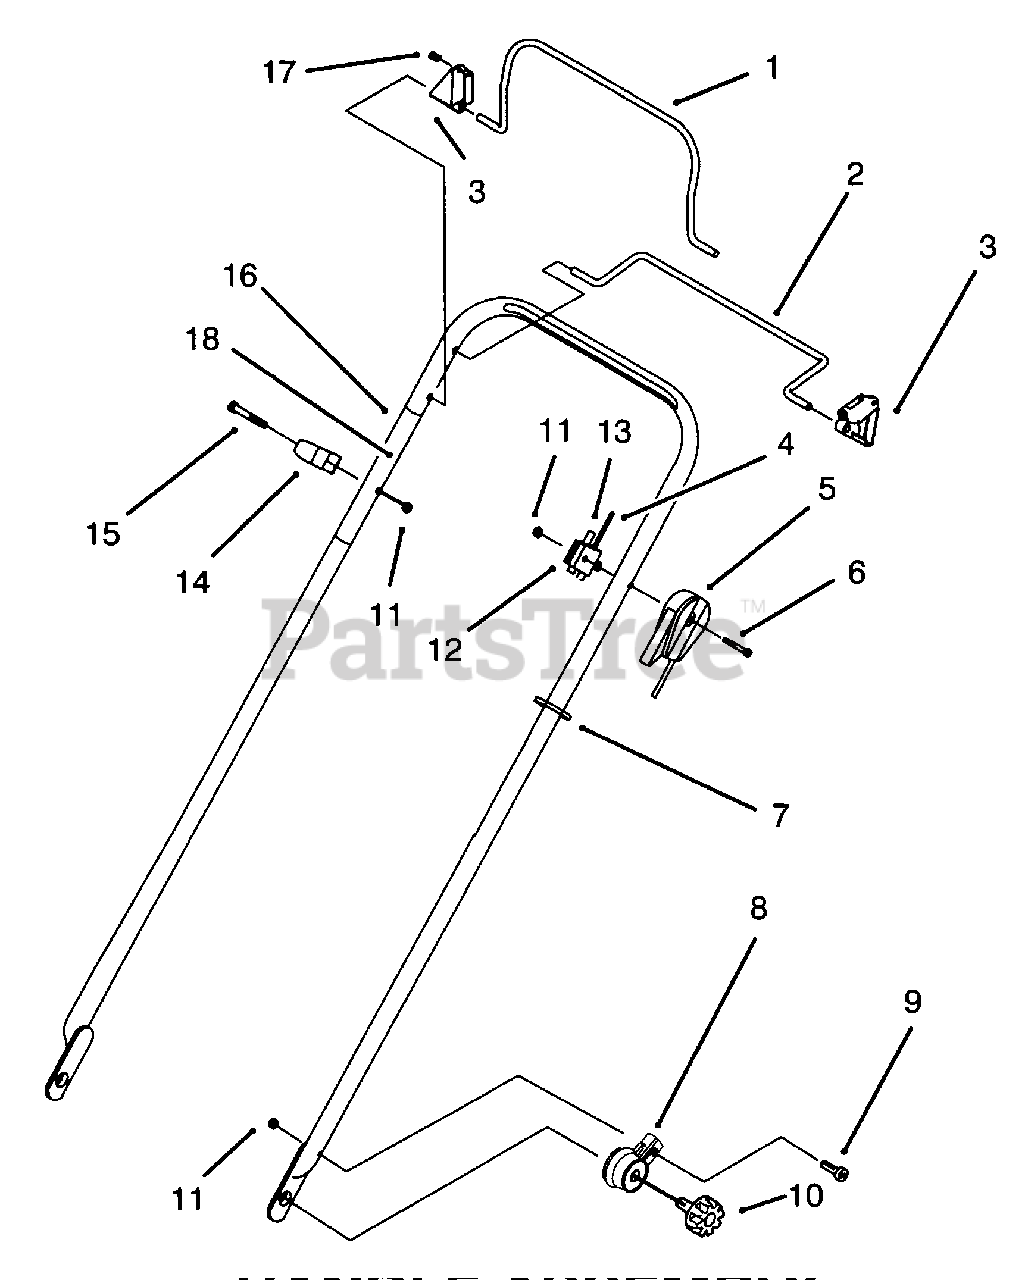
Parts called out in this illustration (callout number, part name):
1	Bail-Brake Int'l
2	Bail-SP Control Int'l
3	Stop-Pivot
4	Cable-Brake
5	Cable-Throttle
6	Screw-Hex Hd. Cap
7	Tie-Cable
8	Handle-Knuckle
9	Screw-Pan Hd.
10	Knob-Handle Mount
11	Nut-Lock
12	Support-Cable
13	Cable-Traction
14	Guide-Rope
15	Screw-Hex Hd. Cap
16	Handle-Int'l
17	Rivet-Pop
18	Decal-Operation
